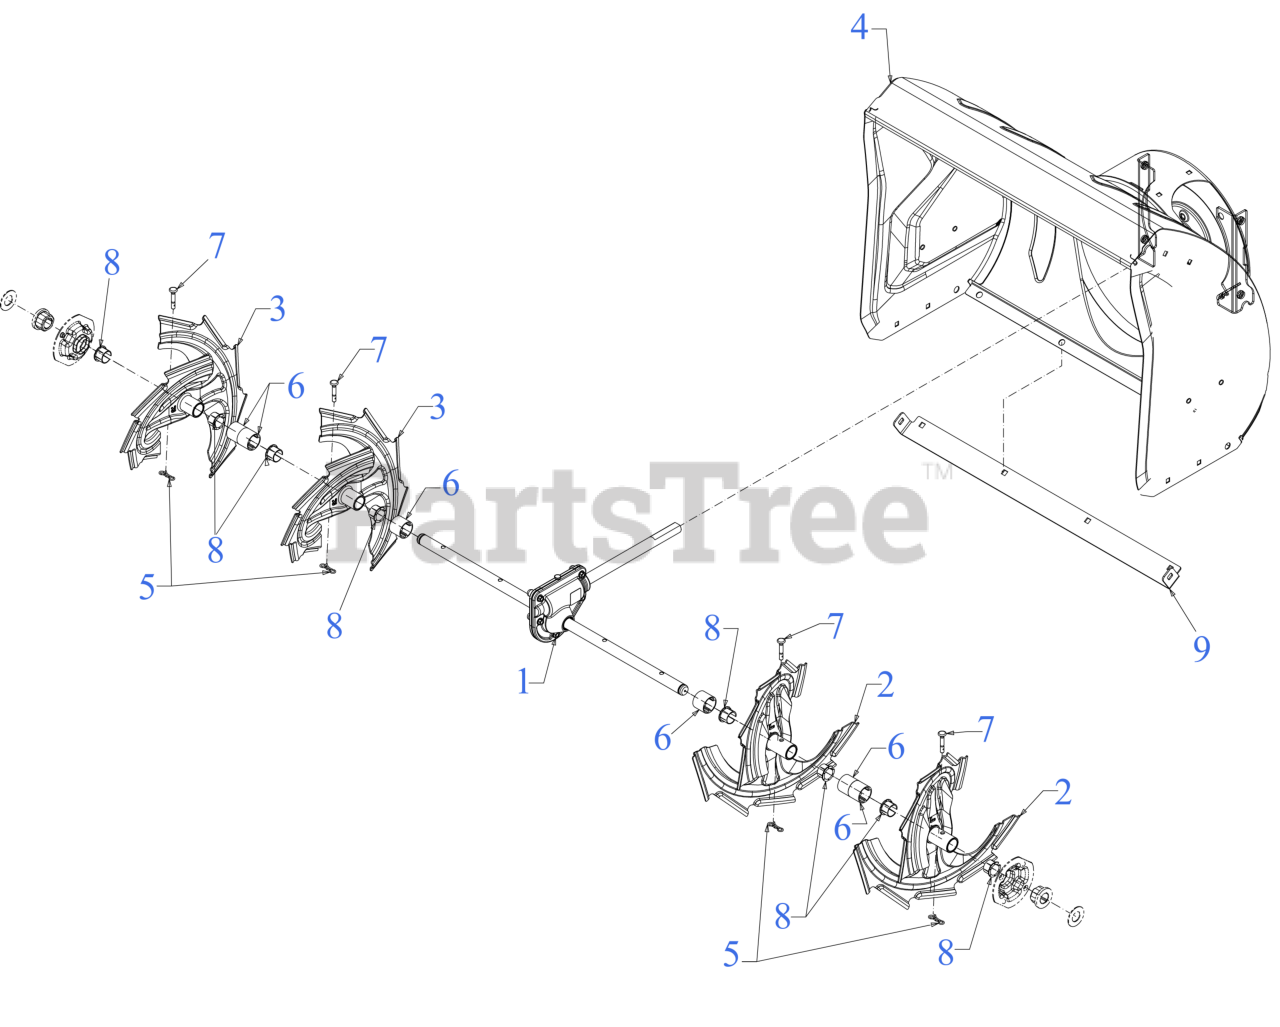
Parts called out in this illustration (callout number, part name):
1	GEARBOX ASSEMBLY 26"
2	10T SPIRAL (LH)
3	10T SPIRAL (RH)
4	26" AUGER HOUSING
5	BOW TIE COTTER PIN 1/4-5/16
6	SPACER 1.25OD x .75ID X1.00 LG
7	SHEAR PIN .25 x 1.50 GR2
7	Troy-Bilt SHEAR PIN 6PK (04124A)
7	Cub Cadet SHEAR PINS (2X SNOW)
7	SHEAR PINS QTY 4
8	FLANGE BUSHING
9	26" SHAVE PLATE
